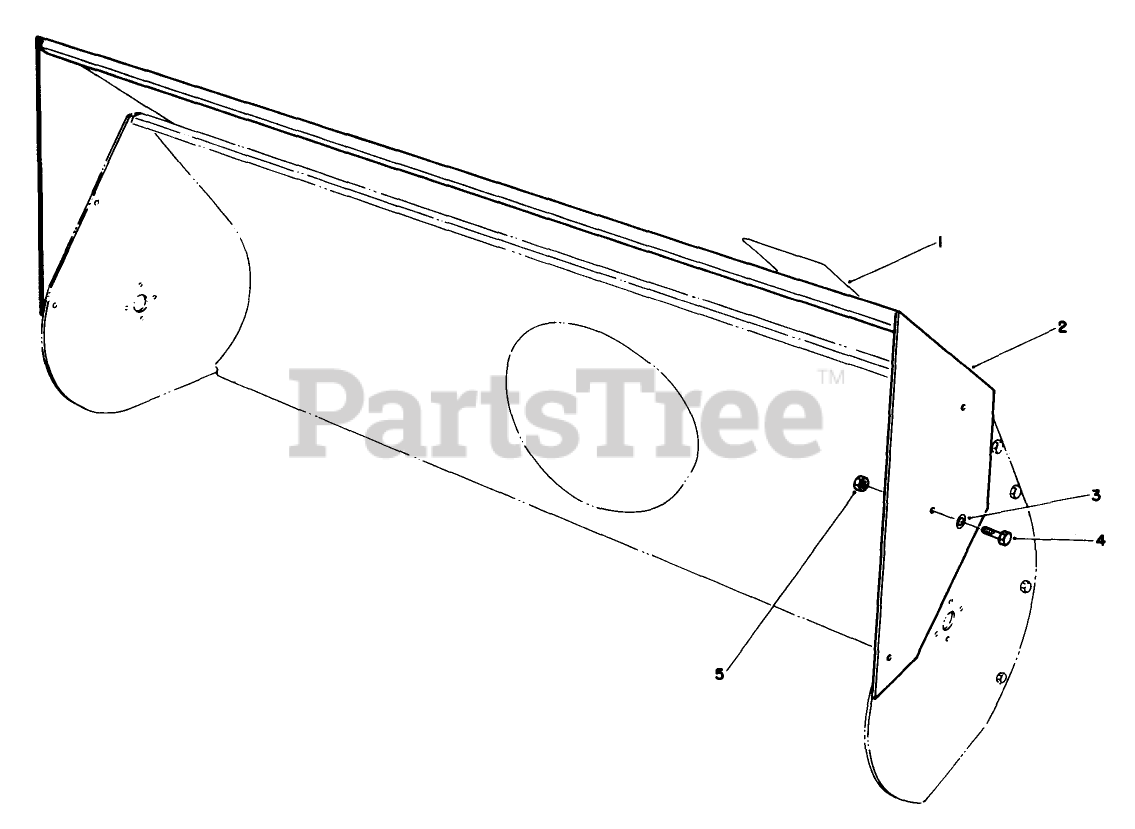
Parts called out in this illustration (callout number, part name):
1	Decal
3	WASHER-FLAT
4	SCREW-HH
5	NUT-LOCK, NI
